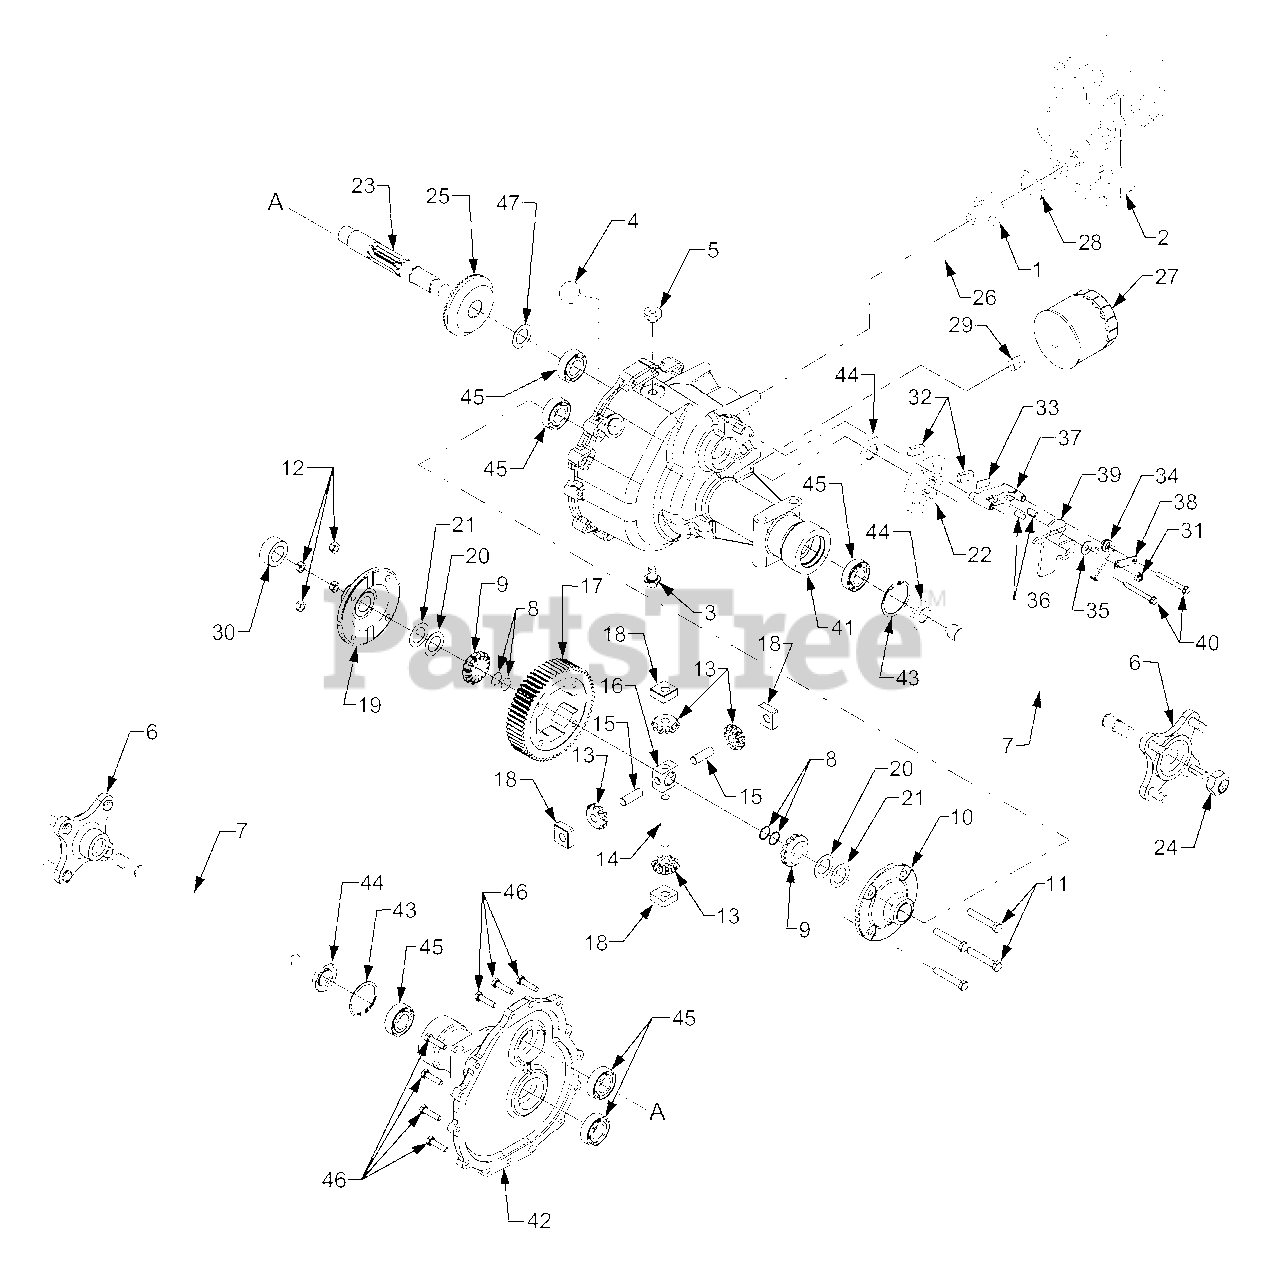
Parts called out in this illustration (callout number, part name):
1	Gear Assembly, Pinion 13T
2	Hydrostatic Transmission Assy.
3	Plug, Drain, M14 x 1.5 x .827
4	Grommet, Rubber
6	Hub Assembly, Wheel
7	Axle Shaft,
8	Retaining Ring
9	Gear, Spur, 14T
10	Housing, Diff. Cover RH
11	Hex Cap Screw, 3/8-24 x 2.25 GR5
12	Nut, Hex Lock, 3/8-24
13	Gear, Differential 10T
14	Shaft, Cross, .5 x 3.485
15	Shaft, Cross, Special
16	Differential Pinion Block
17	Gear, Spur 60T
18	Block, Thrust Miter
19	Housing, Differential Cover LH
20	Washer, Flat, 1.0 x 1.56 x .040
21	Washer, Flat, 1.0 x 1.56 x .020
22	Disc, Brake
23	Shaft, Output 9T
24	Nut, Lock, 3/4-16
25	Gear, Bevel 54T
26	Seal, Gland O-Ring
27	Filter, Oil
28	Washer, Spring
29	Fitting, Filter Nipple
30	Spacer, Axle, 1.0 x 1.665 x .71
31	Nut, Hex Insert Lock, 5/16-24
32	Pad, Brake
33	Plate, Puck
34	Spring, Torsion
35	Washer, Flat, .343 x .88 x .062
36	Pin, Brake Actuator
37	Yoke, Brake
38	Bracket, Brake Anti-Rotation
39	Arm, Brake Actuator
40	Screw, Hex Wash. Hd. Tapp 1/4-20 x 2.375
41	Housing, RH
42	Housing, LH
43	Retaining, Ring
44	Seal, Oil, 1.0 ID
45	Bearing, Ball
46	Screw, Hex Cap Locking 5/16-18 x 1.25 GR5
47	Washer, Flat, 1.0 x 1.56 x .030
